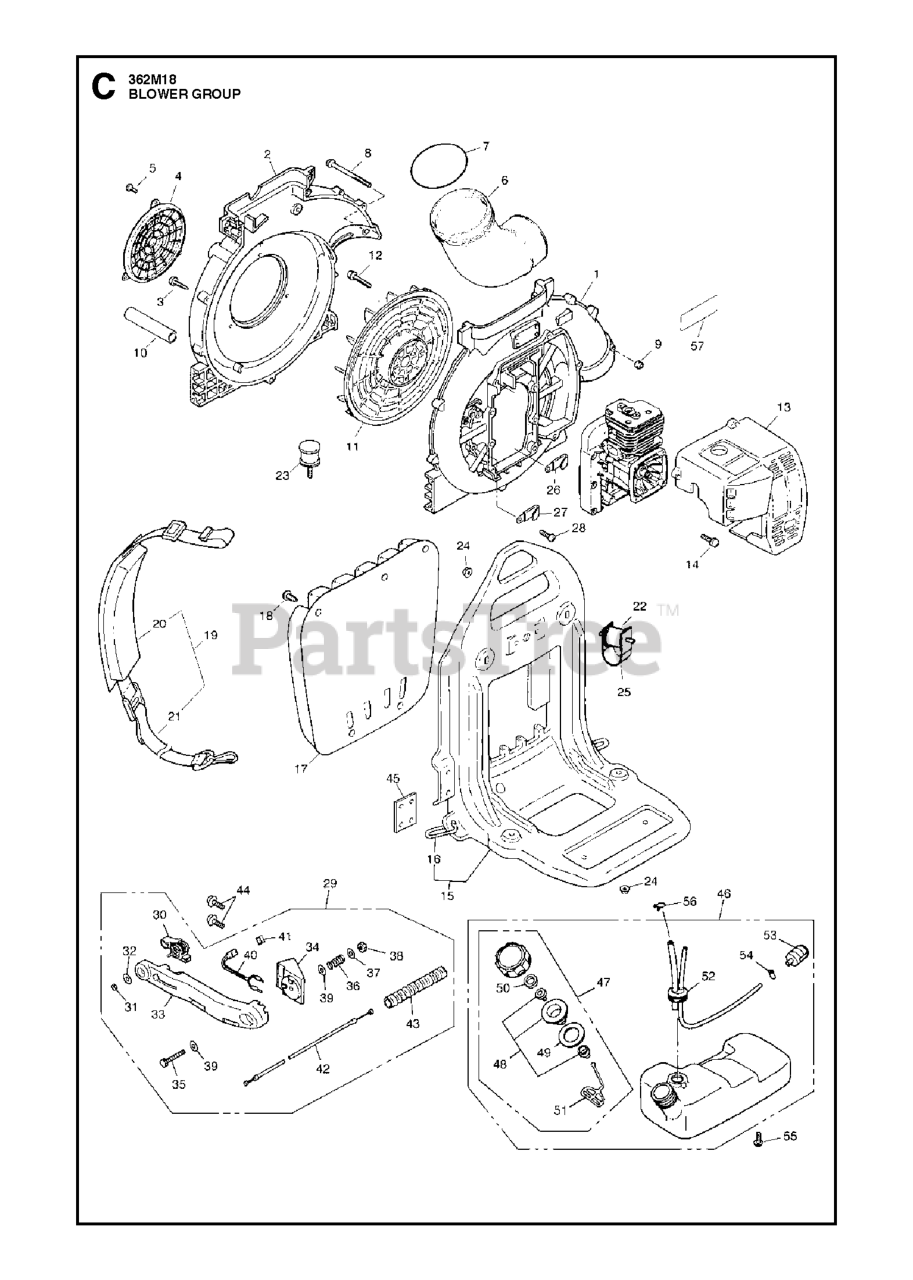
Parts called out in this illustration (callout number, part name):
10	TUBE
27	CLAMP
29	HANDLE ASSY
32	WASHER
37	WASHER Z349525440
38	NUT 8488646000
40	KILL SWITCH
41	CAP SWITCH
42	RP_CABLE COMP
47	ASSY FUEL CAP
53	FILTER ASSY
